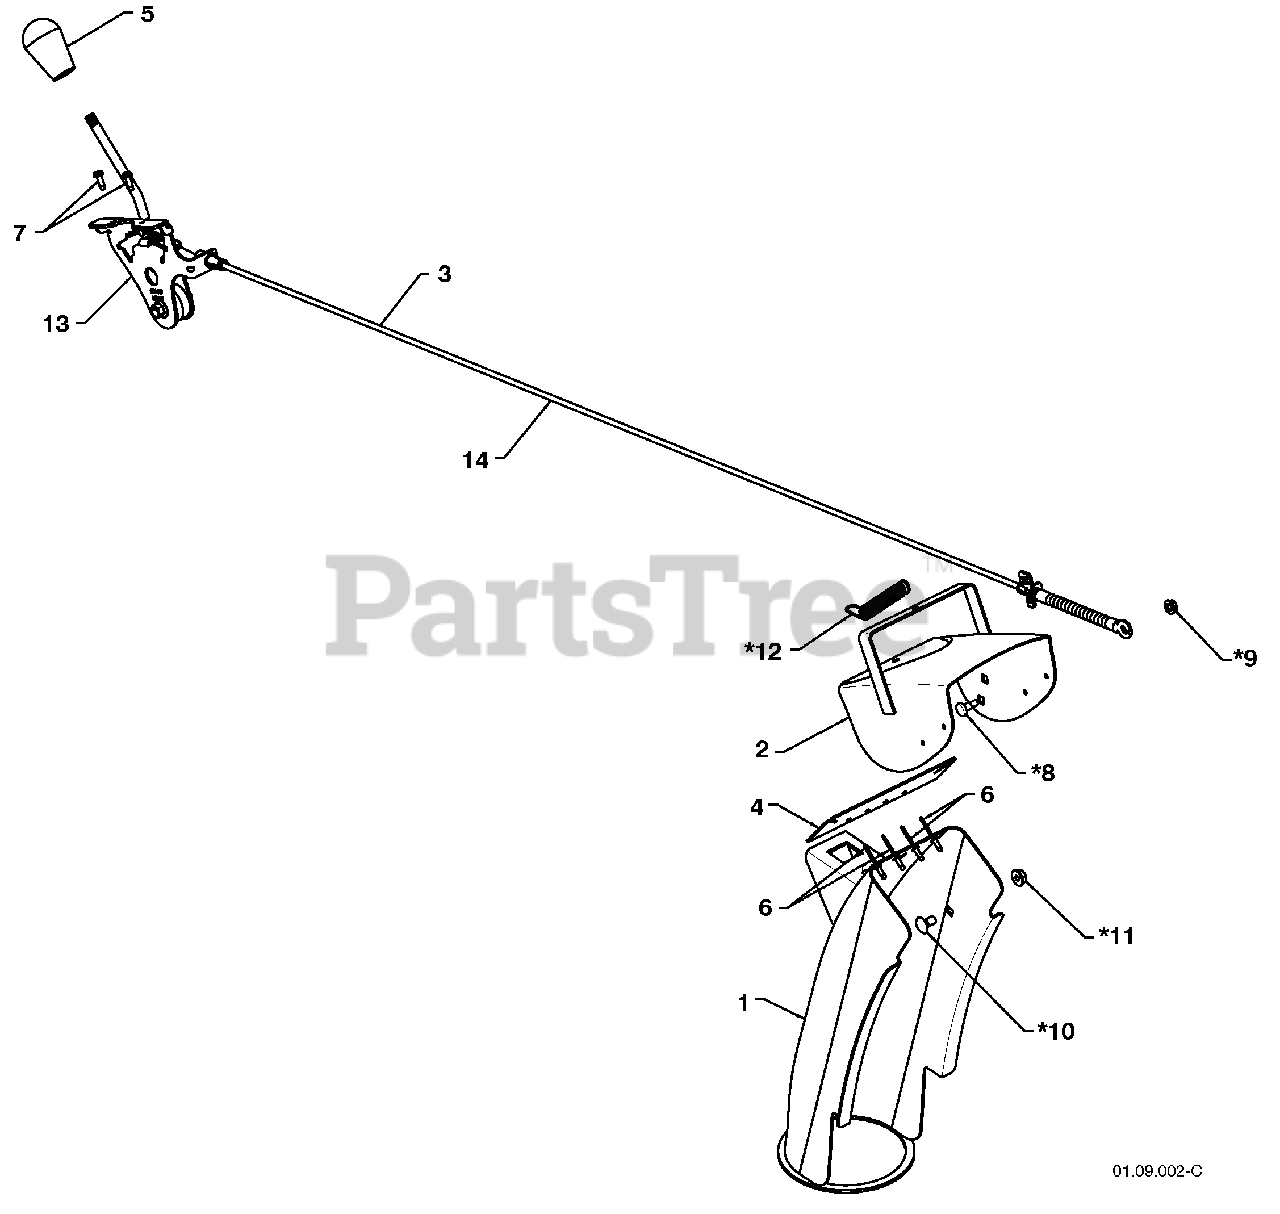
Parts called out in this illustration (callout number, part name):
1	CHUTE WELDMENT
2	DEFLECTOR WELDMENT
3	DEFLECTOR CONTROL ASSEMBLY
4	DEFLECTOR SEAL
5	KNOB BLACK
6	POP RIVET
7	SCREW 10-24 X .625
8	SHOULDER SCREW
9	NUT 1/4-20
10	CARRIAGE BOLT 5/16-18 X .50
11	NUT 5/16-18
12	DEFLECTOR SPRING
13	DEFLECTOR CONTROL HEAD
14	DEFLECTOR CONTROL CABLE
